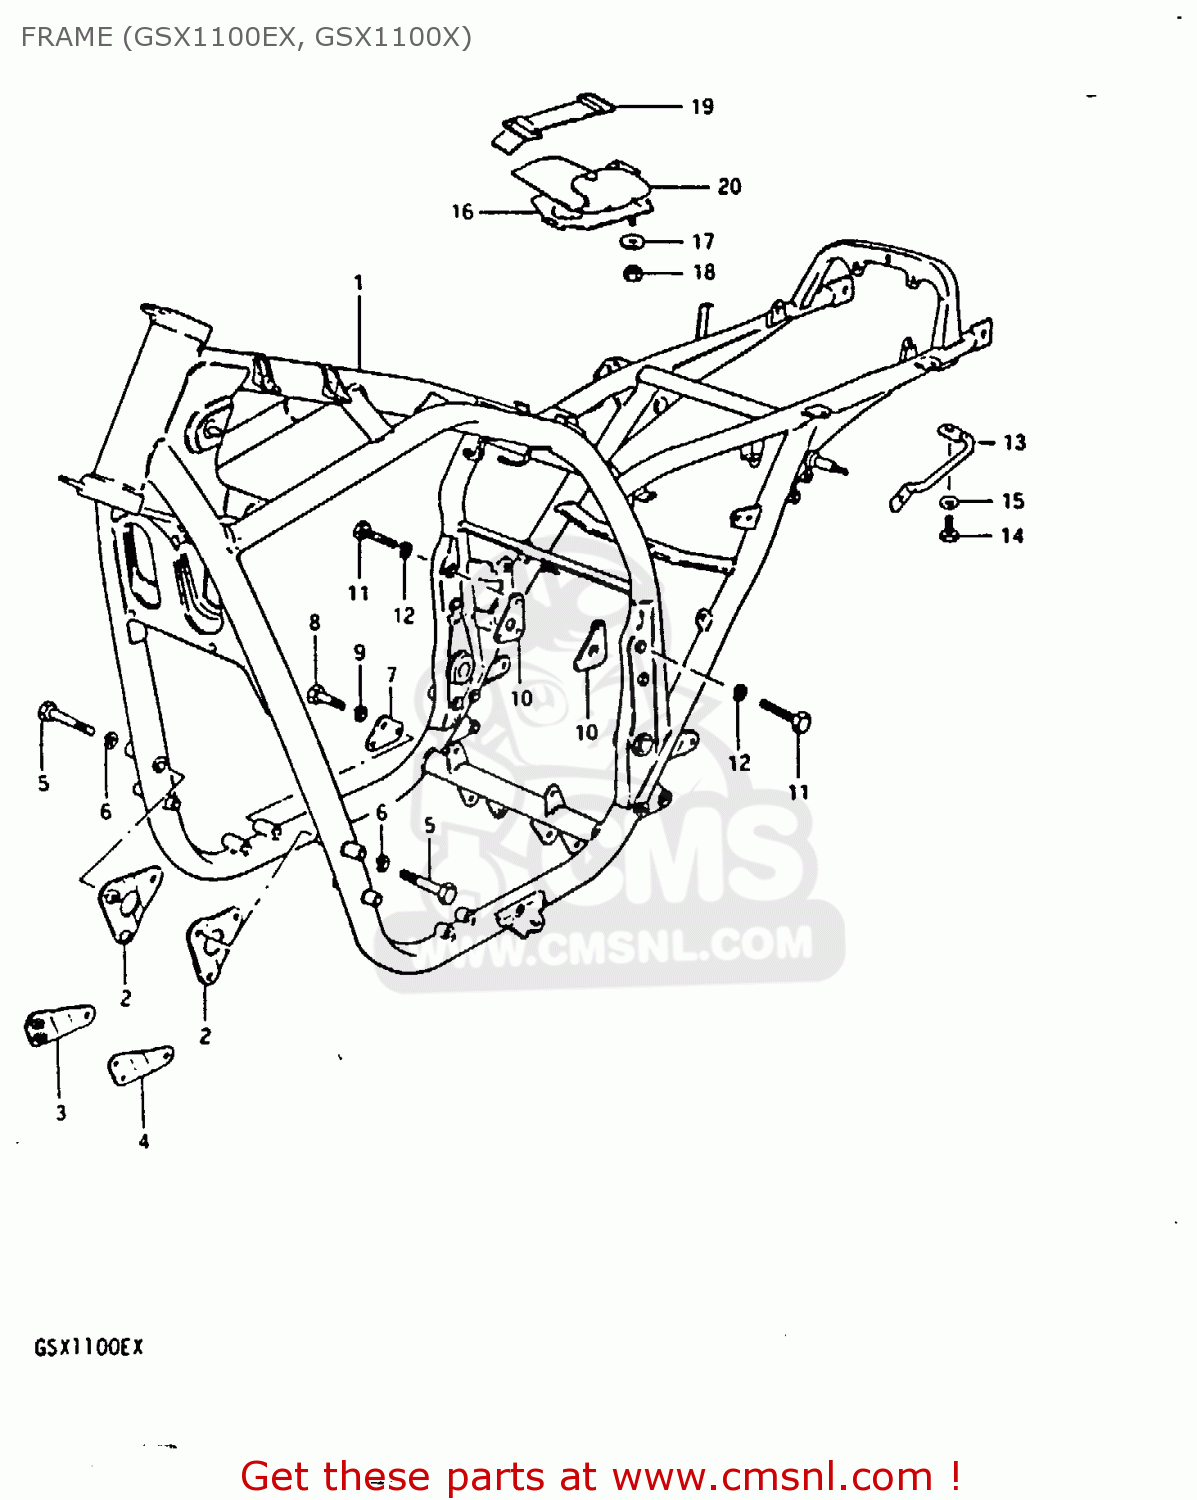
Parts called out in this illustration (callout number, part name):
1	FRAME (BLACK)
2	PLATE,ENG MTG NO.1
3	PLATE, NO.1 RH (BLACK)
4	PLATE, NO.1 LH (BLACK)
5	BOLT
6	LOCK WASHER
7	PLATE,ENGINE MOUNTING
8	BOLT
9	LOCK WASHER
10	PLATE,ENGINE MOUNTING
11	BOLT
12	LOCK WASHER
13	GRIP,FRAME
14	BOLT
15	WASHER
16	HOLDER,TOOL
17	WASHER
18	NUT
19	BAND
20	TOOL SET
